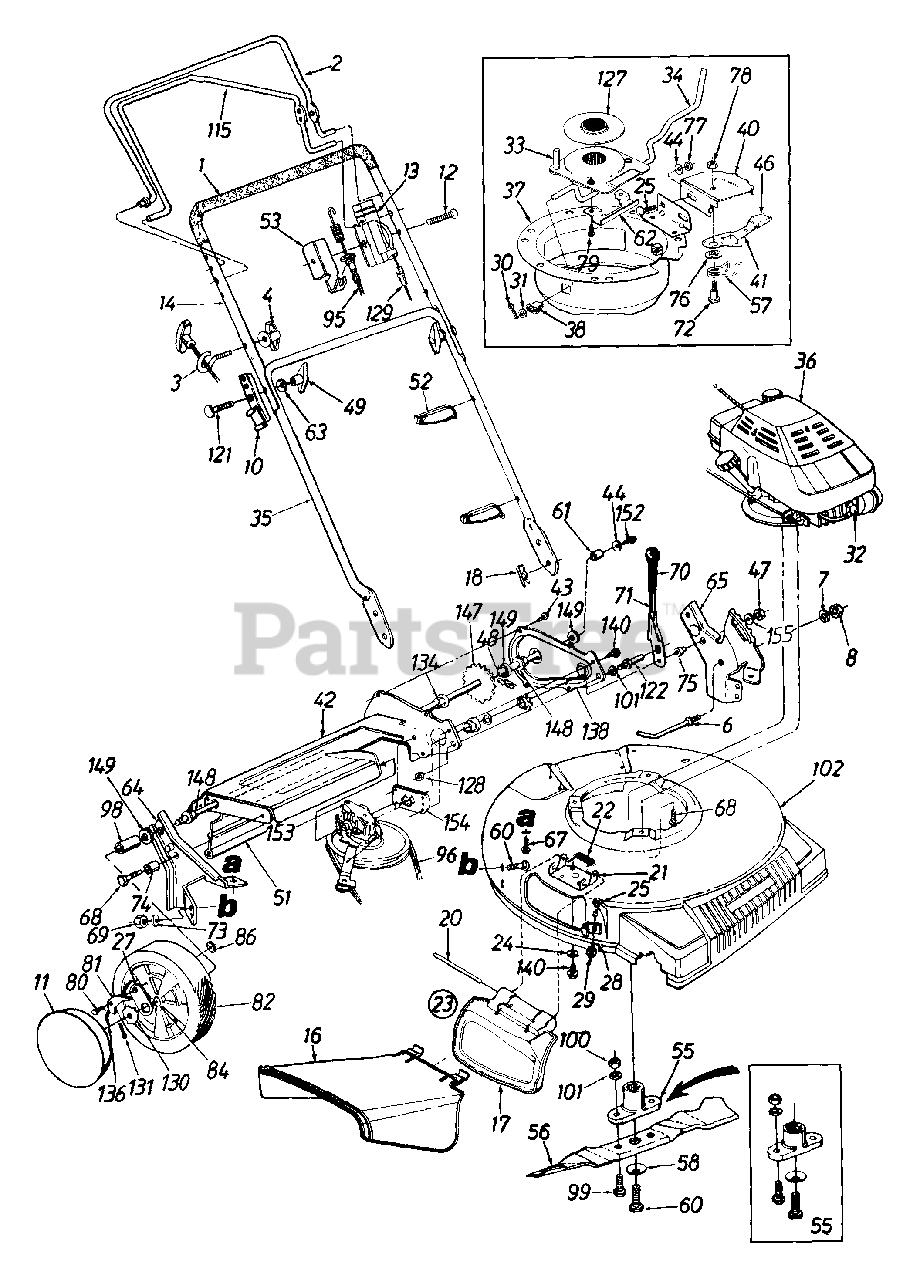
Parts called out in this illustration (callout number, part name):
1	Grip
3	Rope Guide
4	Handle Knob 1/4-20 Thd.
6	Belt Guard
7	L-Wash. 1/4" I.D.
8	Hex Nut 1/4-20 Thd.
10	Grass Catcher Bracket
11	Hub Cap
12	Oval C-Sunk Mach. Scr.
13	Throttle Body
17	Mulch Plug
18	Internal Cotter Pin 5/16" Dia.
20	Hinge Pin
22	Torsion Spring
23	Mulch Plug Ass'y. Comp.
24	Bell-Wash..265" I.D. x .75" O.D
25	Carriage Bolt 1/4-20 x .5" Lg.
27	Pawl Plate
30	Cotter Pin 3/32" Dia. x .75"
31	Fl-Wash..328" I.D. x .68"
32	Spark Plug Insulator
33	Lower Pulley Half Ass'y.
34	Shift Rod
36	Engine - Craftsman
44	Bell-Wash. 1/4" I.D.
46	Spring Lever Knob
47	Hex Patch L-Nut 3/8-24 Thd.
48	#48 Chain .500" Pitch x 38 Links
49	Hand Knob
51	Rear Flap 3.75" x 17.5" Lg.
52	Cable Tie
56	21" Mulching Blade
57	Torsion Spring
58	Bell-Wash..47" I.D. x 1.14" O.D
60	Hex Bolt 7/16-20 x 2.5"
61	Spacer .513" I.D.
67	Hex B-Tap Scr. 5/16-18
68	Hex TT-Tap Scr. 3/8-16
69	Hex Nut 5/16-18 Thd.
71	Height Adj. Lever
72	Shld. Bolt .437" Dia.
73	Bell-Wash. 5/16" I.D.
74	Spacer .383" I.D.
75	Shld. Spacer .5" Dia.
76	Shld. Spacer .5" Dia. x .134"
77	Hex L-Nut 1/4-20 Thd.
78	Hex L-Nut 5/16-18 Thd.
79	Hex Wash. Hd. Tap Scr. 1/4-20 x .38" Lg.
80	Shld. Scr..342" Dia. x .268
81	Pawl
82	Wheel Ass'y. Comp.-- Rear
84	Sleeve Bearing 1/2" I.D.
86	Weld Top L-Nut 1/4-20 Thd.
95	S.P. Cable
96	"V"-Belt
98	Sleeve .526" I.D.
99	Hex Bolt 3/8-24 x 1.0" Lg.
100	Hex Nut 3/8-24 Thd.
101	L-Wash. 3/8" I.D.
121	Curved Hd. Bolt 5/16-18 x 2" Lg.
122	Shld. Pin 1.43" Lg.
127	Pulley Half - Serrated
128	Hex Jam Nut 3/8-24 Thd.
129	Control Cable - 51"
130	Ratchet Wheel 1.62" O.D.
131	Cotter Pin 1/8" Dia. x 1"
134	Hex Flange Bearing
136	Spring - Nylon
147	Rear Shaft Ass'y. 21.44" Lg.
148	Hex Flange Brg..506" I.D.
149	Fl-Wash..531" I.D. x .930"
152	Hex Bolt 1/4-20 x .62" Lg. (Grade 5)
153	Transmission Comp. (See Breakdown)
155	Fl-Wash..385" I.D. x .87" O.D.
